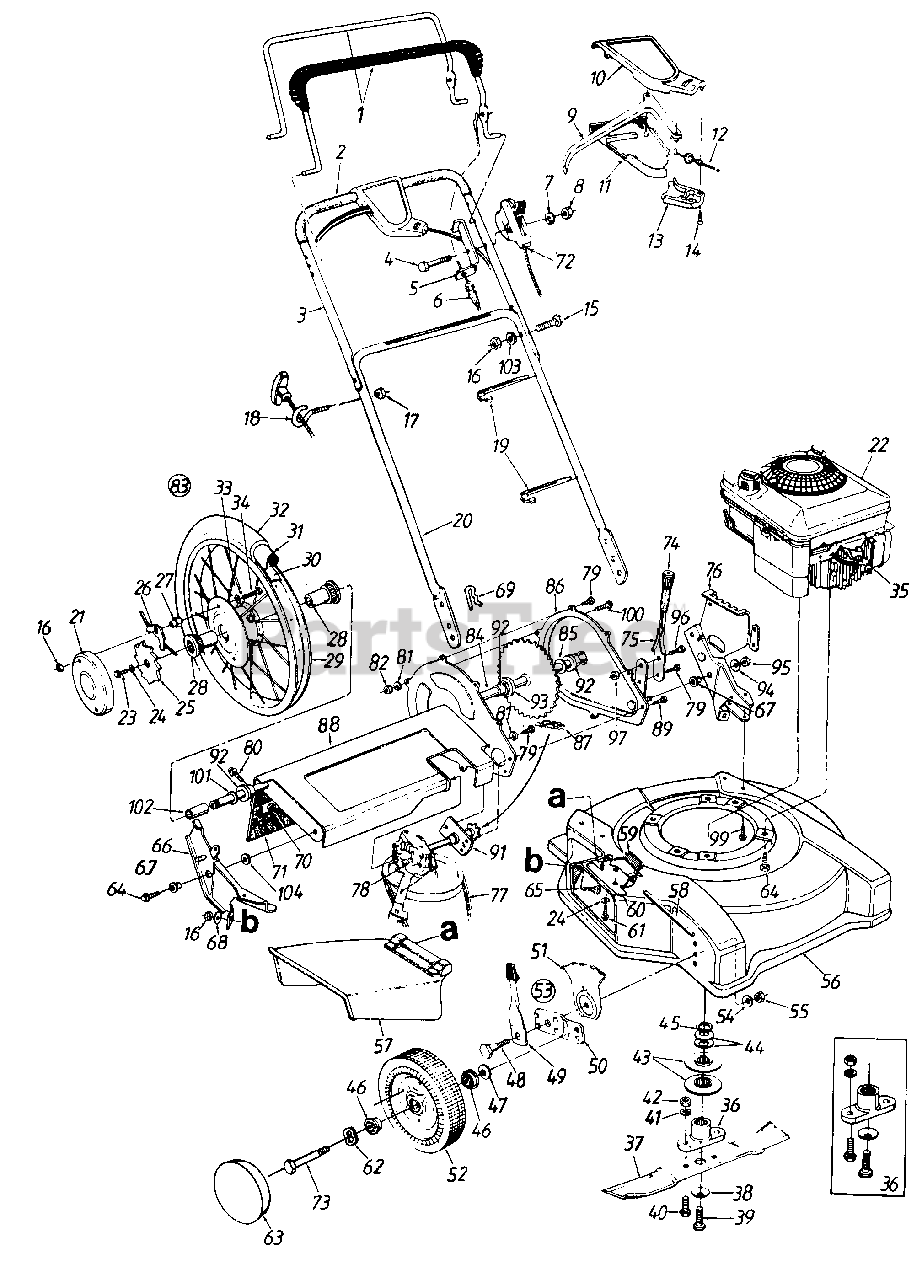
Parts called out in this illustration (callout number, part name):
1	Control Handle Ass'y.
2	Foam Grip
3	Upper Handle
4	Hex Bolt 1/4-20 x 1.875" Lg.*
5	Cable Mtg. Brkt.
6	Control Cable-36" Lg.
7	Spring Wash. .265" I.D.
8	Hex Nut 1/4-20 Thd.*
9	Control Lever
10	Control Cover Half-Upper
11	Control Cover Half-Lower
12	Self-Propelled Cable-44" Lg.
13	Cable Mounting Cap
14	FI IC Sunk Hd. Tap Scr. #10 x .75" Lg.
15	Curved Carr. Bolt 5/16-18 x 1.38" Lg.
16	Hex Nut 5/16-18 Thd.*
17	Hex L-Nut 1/4-20 Thd.
18	Rope Guide
19	Cable Tie
20	Lower Handle
21	Wheel Cover
22	Engine
23	Hex Bolt 1/4-20 x .75" Lg. (Grade 5)
24	Bell-Wash. 1/4" I.D.
25	Wheel Ratchet
26	Pawl and Spring Ass'y.
27	Special Hex Nut 5/16-18 Thd.
28	Flange Bearing .63" I.D.
29	Rim Ass'y. Only 16" x 2.1
30	Rimstrip 16" x 7/8"
31	Inner Tube 16" x 2.12"
32	Chevron Tire 16" x 2.125"
33	Intern. L-Wash. 5/16" I.D.
34	Hex Bolt 5/16-18 x 1.0" (Grade 5)
35	Spark Plug Boot
36	Blade Adapter Kit
37	22" Blade
38	Bell-Wash..46" I.D.
39	Hex Bolt 7/16-20 x 1.5" Lg. (Grade 5)
40	Hex Bolt 3/8-24 x 1" Lg.
41	L-Wash. 3/8" I.D.*
42	Hex Nut 3/8-24 Thd.*
43	Pulley Half
44	Bell-Wash. 1.01" I.D.
45	Crankshaft Spacer
46	Ball Bearing 1/2" I.D.
47	Bell-Wash..38" I.D.
48	Shld. Bolt .5"
49	Spring Lever Ass'y. w/Knob
51	Height Adj. Plate
52	Wheel Ass'y. Comp. (Steel)
53	Height Adj. Ass'y. Comp.-R.H.
54	Bell-Wash. .39" I.D. x 1.38"
55	Hex Nut 3/8-16 Thd.
58	Hinge Pin
59	Torsion Spring
60	Adapter Plate
61	Hex TT-Tap Scr. 1/4-20 x .5"
62	Wave Wash. .53" I.D. x .78"
63	Hub Cap (5-1/2" Dia.)
64	Hex TT-Tap Scr. 3/8-16 x 1"
65	Carriage Bolt 5/16-18 x .62" Lg.
66	Handle Brkt. Ass'y.-R.H.
67	Shld. Spacer .5" x .10"
68	Bell-Wash. 5/16" I.D.
69	Intern. Cotter Pin 5/16" Dia.
70	Retaining Strip
71	Rear Flap
72	Throttle Control Ass'y. Comp.- 49" Lg.
73	Front Axle Bolt
75	Height Adjustment Lever
78	Transmission Comp.
79	Hex B-Tap Scr. 1/4 x .38" Lg.
80	Hex AB-Tap Scr. 1/4 x .62" Lg.
81	L-Wash. 1/4" I.D.
82	Hex Nut 1/4-20 Thd.
83	Wheel Ass'y. Comp.
84	Sprocket and Axle Ass'y.
85	Fl-Wash. .635" I.D. x 1.0" O.D.
92	Hex Flange Brg. .631" I.D.
93	Spacer .63" I.D. x 1.25"
94	Fl-Wash. .385" I.D. x .87" O.D.
95	Hex L-Nut 3/8-24 Thd.
96	Hex Bolt 3/8-16 x .62" Lg.
97	Flanged L-Nut 3/8-16 Thd.
99	Hex B-Tap Scr. 5/16-18 x .5"
100	Hex Bolt 1/4-20 x .5" Lg.
101	Fl-Wash. .632" I.D. x .943"
102	Spacer .628" I.D. x .875"
103	L-Wash. 1/4" I.D.
104	Fl-Wash. .38" I.D. x 1" O.D.
